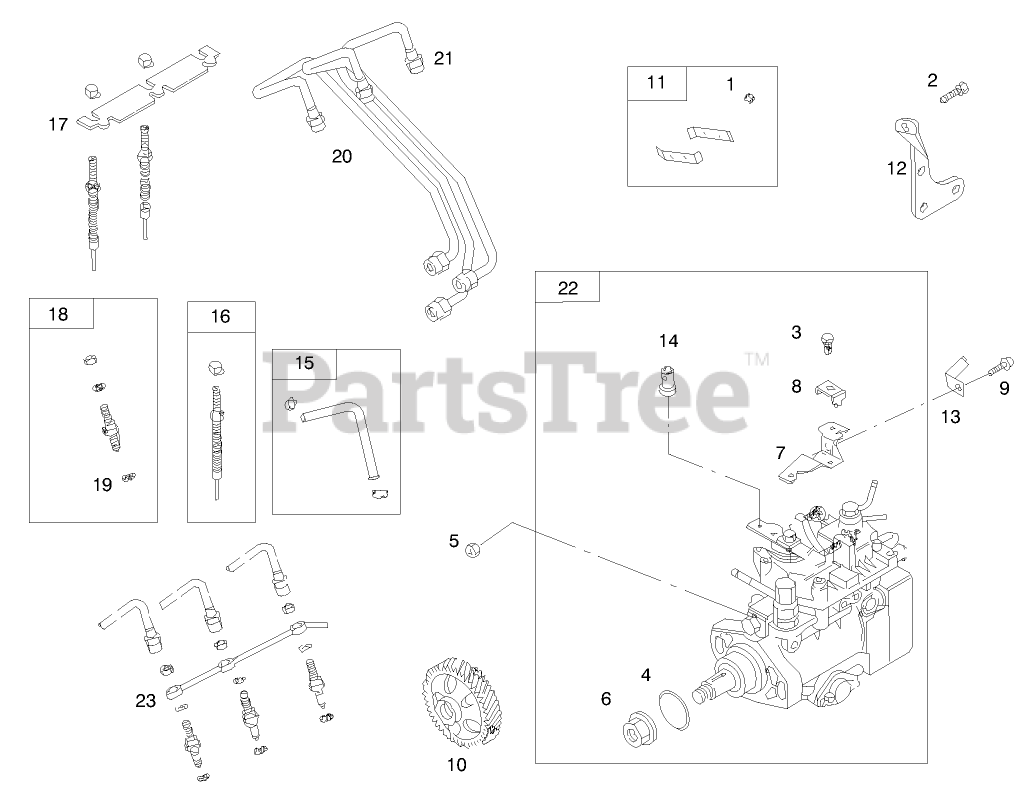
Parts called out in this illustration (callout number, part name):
1	SCREW-HEX
2	SCREW-HEX
4	O-RING
5	NUT-HEX, METRIC
6	NUT-HEX, METRIC
7	BRACKET-CLAMP, CASING
9	SCREW-HEX
10	GEAR-DRIVE
11	CLAMP
12	BRACKET-SUPPORT
14	CLAMP-SWIVEL
15	HOSE / CLAMP ASM
17	STRAP-PLUG, GLOW
18	NOZZLE-INJECTOR
19	SEAT-INJECTOR
20	PIPE-INJECTOR, NO. 2
21	PIPE-INJECTOR, NO. 3
22	PUMP-INJECTION
23	PIPE-RETURN, FUEL
